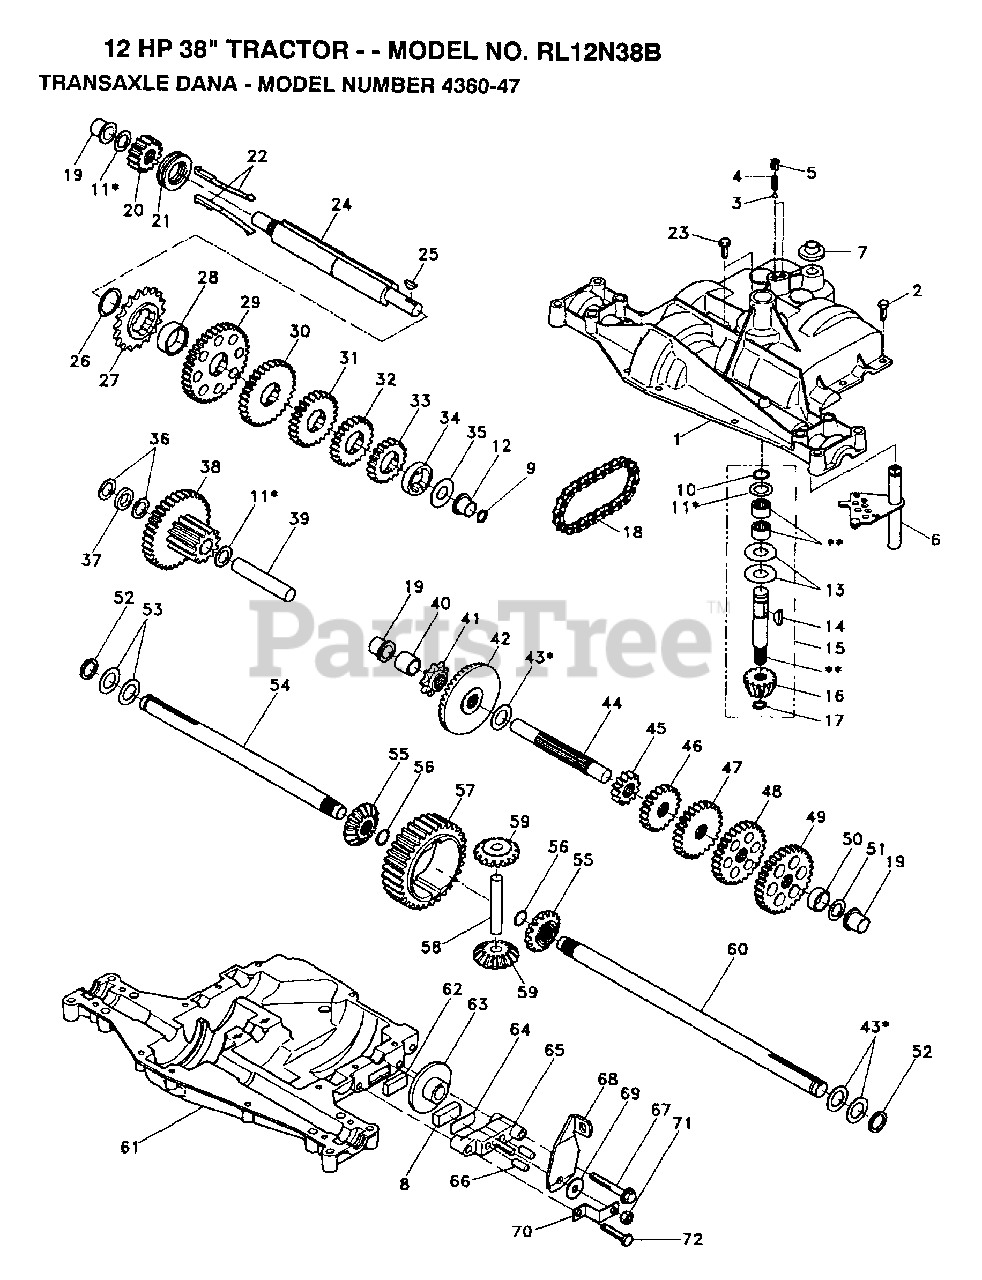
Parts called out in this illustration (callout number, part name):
4	"SPRING, DETENT LT"
5	"SCREW, SET LT"
6	KIT SHIFTER ASM
7	SHIFTER BOOT
8	NUT.LOCK.5/16-24
9	SQUARE RING
10	RETAINING RING LT
11	ASM KIT SHIM 4689
12	"FLANGE, BEARING"
13	WASHER T
14	WOODRUFF KEY
15	AS KIT INPUT SHFT
16	PINION 14T T
17	"RING,RETAINING LT"
18	"CHAIN,24 PTCH LT"
19	BEARING.FLNG.5510
20	GEAR SPUR 14T
21	COLLAR CLUTCH
22	ASM KIT CLTCH KEY
23	SCREW TAP W/SEAL
24	SHAFT INTERM
25	WOODRUFF KEY
26	"RING,RETAINING LT"
27	SPROCKET 18T T
28	SPACER YT
29	KIT.GEAR.12/37TH
31	GEAR 25T LT
32	SPUR GEAR 19T
33	SPACER
34	"SCREW, TAPPING LT"
35	"WASHER, PLAIN LT"
36	WASHER 025
37	SPACER
38	ASSM GEAR COMB
39	SHAFT IDLER
40	SPACER T
41	SPROCKET 9T LT
43	ASM KIT SHIM
44	SHAFT T
47	"GEAR, SPUR 25T LT"
48	"GEAR, SPUR 31T LT"
50	PUCK T
51	WASHER 060
52	NEOPRENE WASHER
53	WASHER 031
55	GEAR 15T T
56	"RING,RETAINING LT"
58	SHAFT T
59	GEAR 1ST T
62	PUCK T
63	BRAKE DISC. T
64	SPACER LT
66	PIN T
69	WASHER LT
